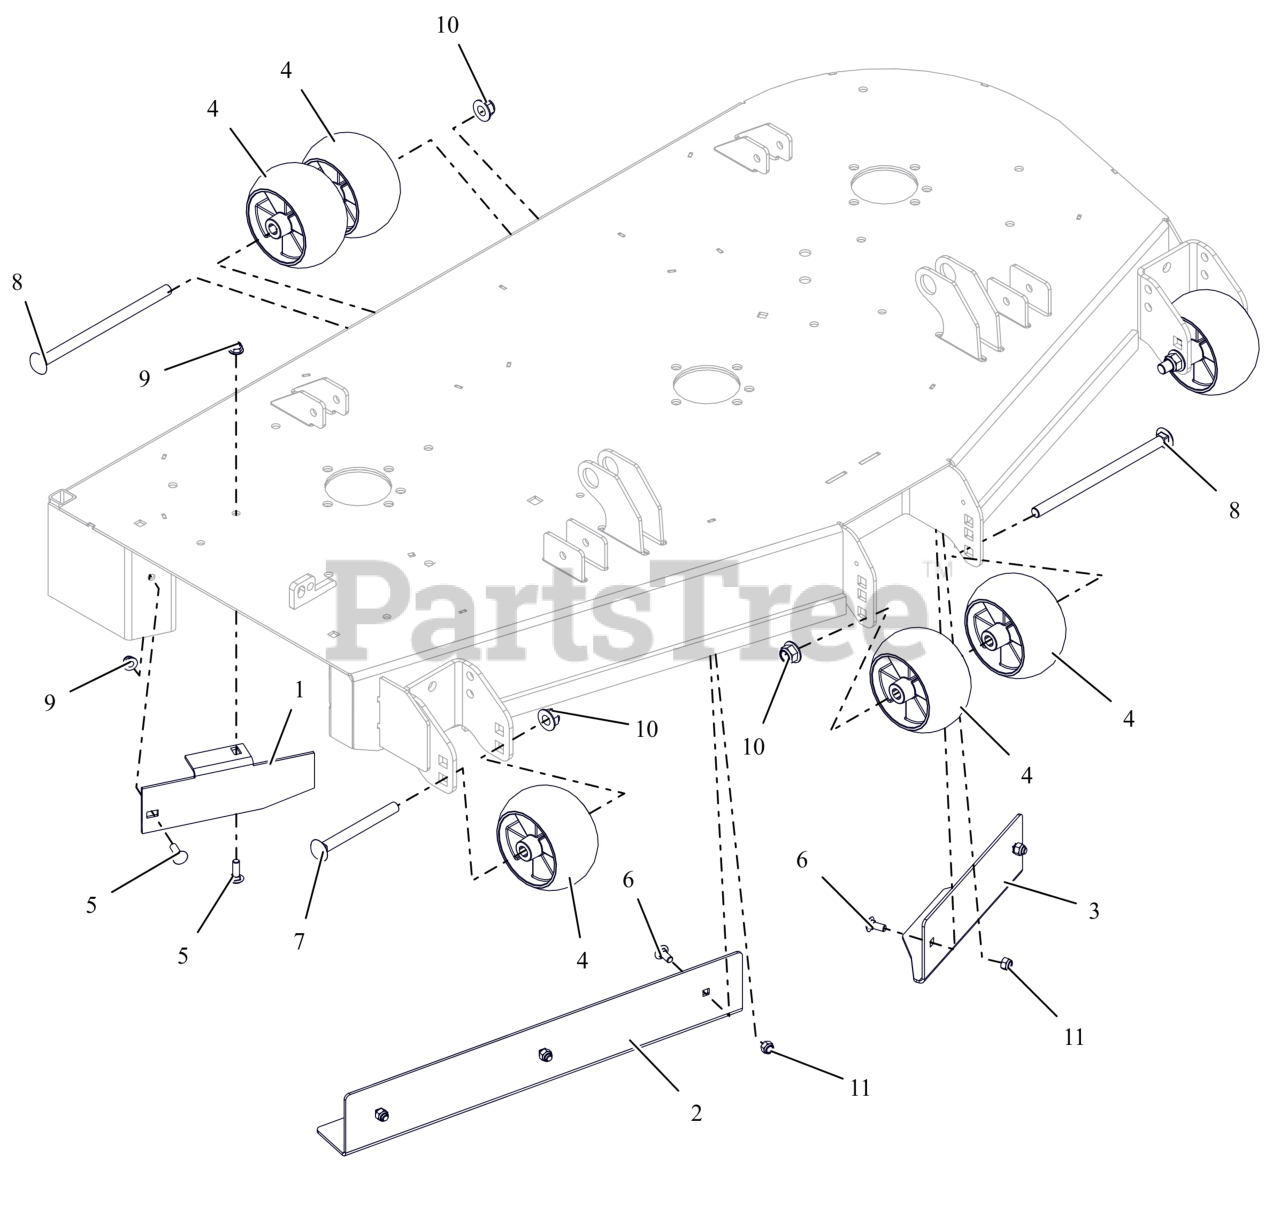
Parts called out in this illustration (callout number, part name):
1	BAFFLE, DISCHARGE, 52"
2	BAFFLE, 52" RH VACUUM (ORANGE)
3	BAFFLE, 52" LH VACUUM (ORANGE)
4	WHEEL, ANTI SCALP - 5X3 CTR W/RIBS
5	BLT,RHSN .31-18X1.00 G5 ZCC
6	BLT,RHSN .31-18X.75 G5 ZCC
7	BLT, RHSN .50-13X5.00 G5 ZCC
8	BTL,RHSN .500-13 X 8.5S G5 ZCC
9	NUT,LK-NYL-FLG .31-18 G5ZC120
10	NUT,NYL-FLG .50-13 GF ZCC
11	NUT,NYL .31-18 G5 ZCC
